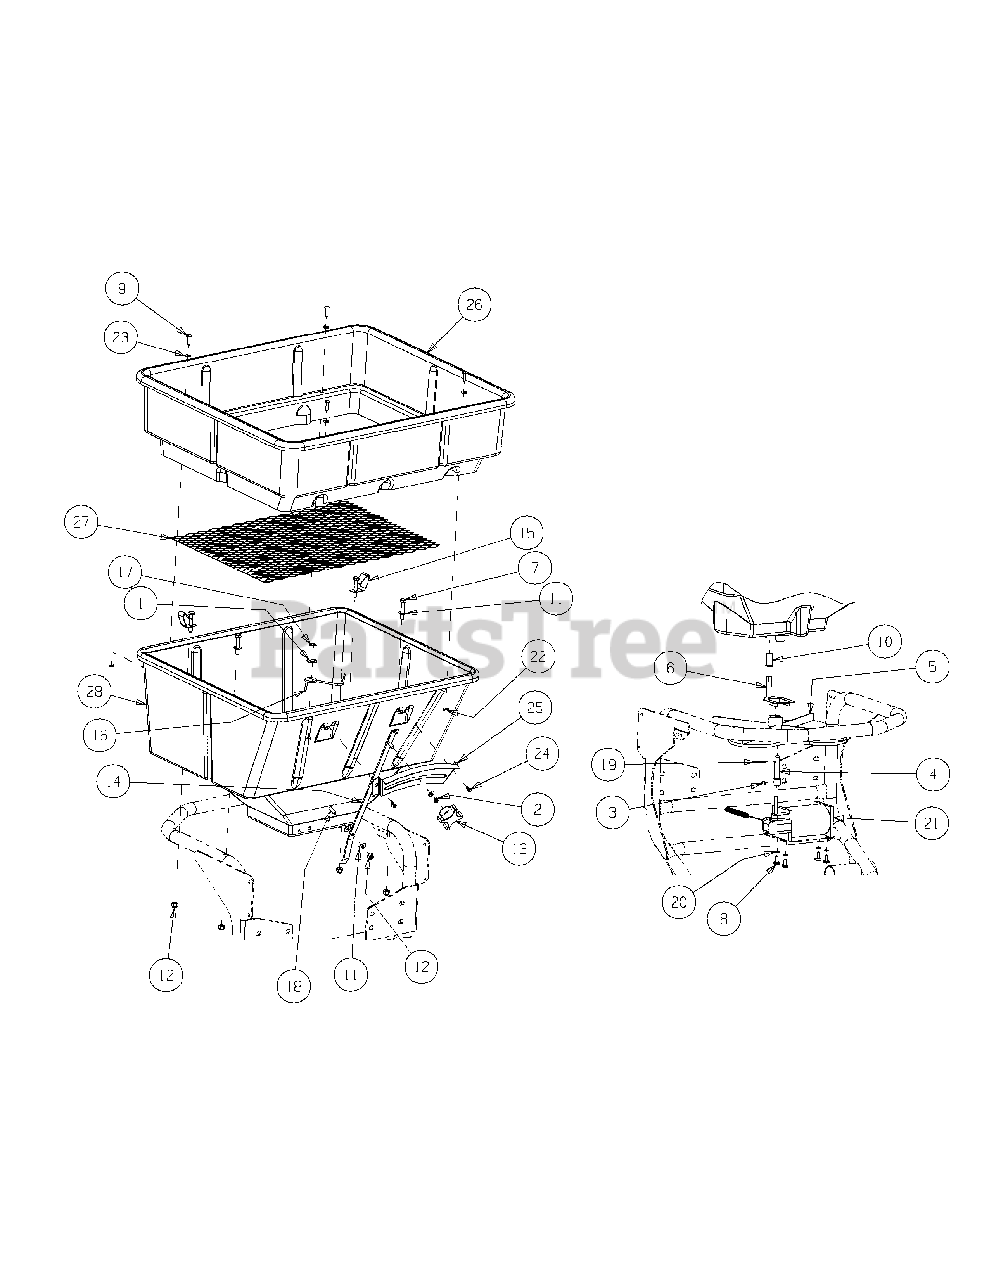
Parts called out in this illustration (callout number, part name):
1	Washer, 3/8
2	Washer, 1/4
3	Set Screw, 5/16-18 x 1/4, SS
4	Impeller Adaptor
6	Cam Agitator Assembly
7	Hex Cap Screw, 1/4-20 x 1.50
8	Machine Screw, 8-32 x .467, SS
9	Machine Screw, 10-24 x 3/4, SS
10	Agitator Bearing
11	Washer, 1/4, SS
12	Nut, 1/4-20, SS
13	Rate Control Knob
14	Rate Control Arm
15	Screen Clip, SS
16	Agitator Arm Assembly
17	Spring Retainer Clip
18	Machine Screw, 1/4-20 x 7/8
19	Roll Pin, 1/8 x 7/8, SS
20	Lock Washer, #8 External Tooth
21	Motor w/ 38" Cord & Plug
22	Nut, 10-24, SS
23	Washer, #8, SS
24	Screw, #8 x 3/8, SS
25	Rate Plate
26	Hopper Extension
27	Screen, SS
28	80# Hopper
